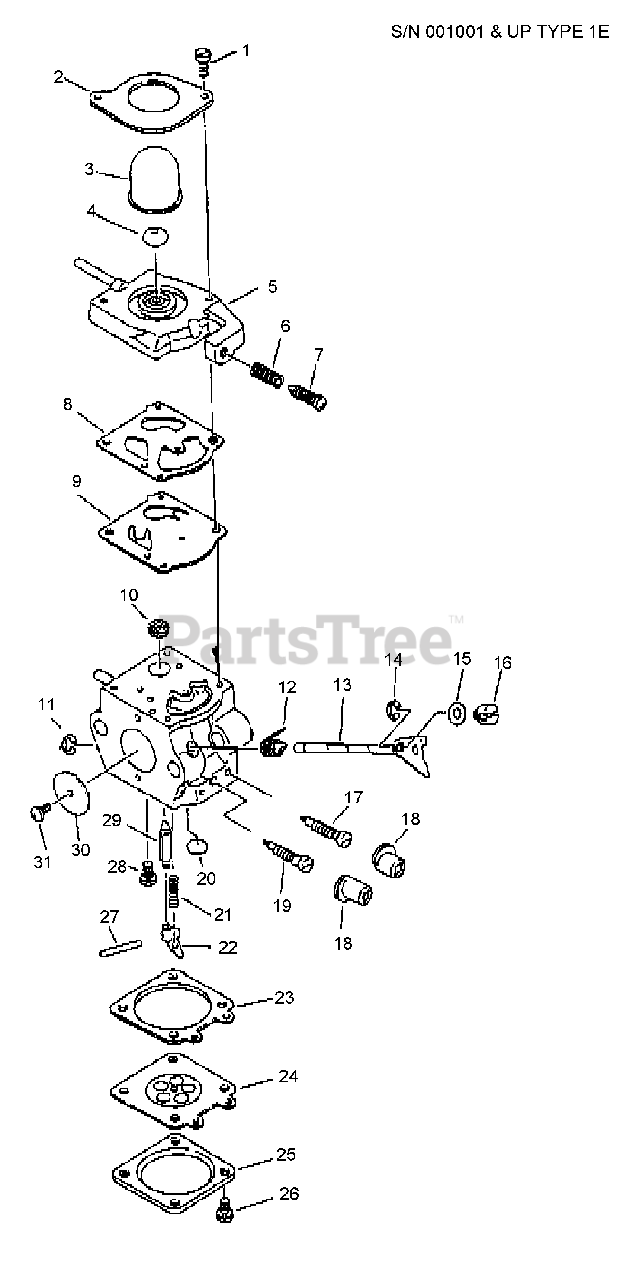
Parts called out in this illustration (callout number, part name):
1	SCREW, PUMP COVER
2	RETAINER, PURGE BULB
3	BULB, PURGE
4	VALVE, CHECK
5	BASE, PURGE
6	SPRING, IDLE ADJUST
7	SCREW, IDLE ADJUST
8	GASKET, PUMP
9	DIAPHRAGM, PUMP
10	STRAINER
11	RING, RETAINING
12	SPRING, THROTTLE RETURN
13	SHAFT, THROTTLE
14	RING, RETAINING
17	NEEDLE - HIGH SPEED
18	CAP, LIMITER
19	NEEDLE - MIXTURE
20	PLUG, WELCH
21	SPRING, METERING LEVER
22	LEVER, METERING
23	GASKET, METERING
24	DIAPHRAGM, METERING
25	COVER, METERING
26	SCREW
27	PIN, METERING LEVER
28	SCREW, METERING LEVER PIN
29	VALVE, INLET NEEDLE
30	VALVE, THROTTLE
